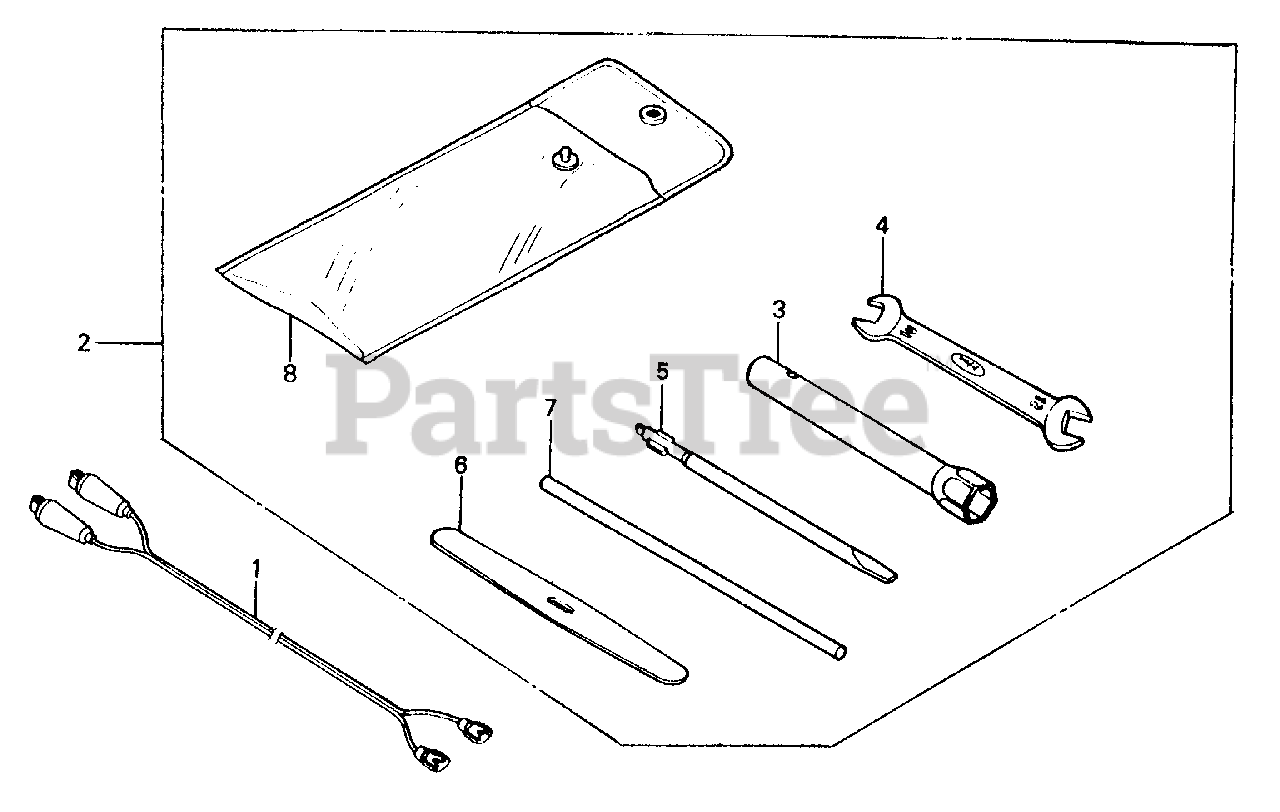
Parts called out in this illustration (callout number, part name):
3	WRENCH, PLUG
4	WRENCH (10X12) (OPEN END)
5	SCREWDRIVER 3, STRAIGHT SLOT (NO.2)
6	LEVER, TIRE
7	BAR A, HANDLE
